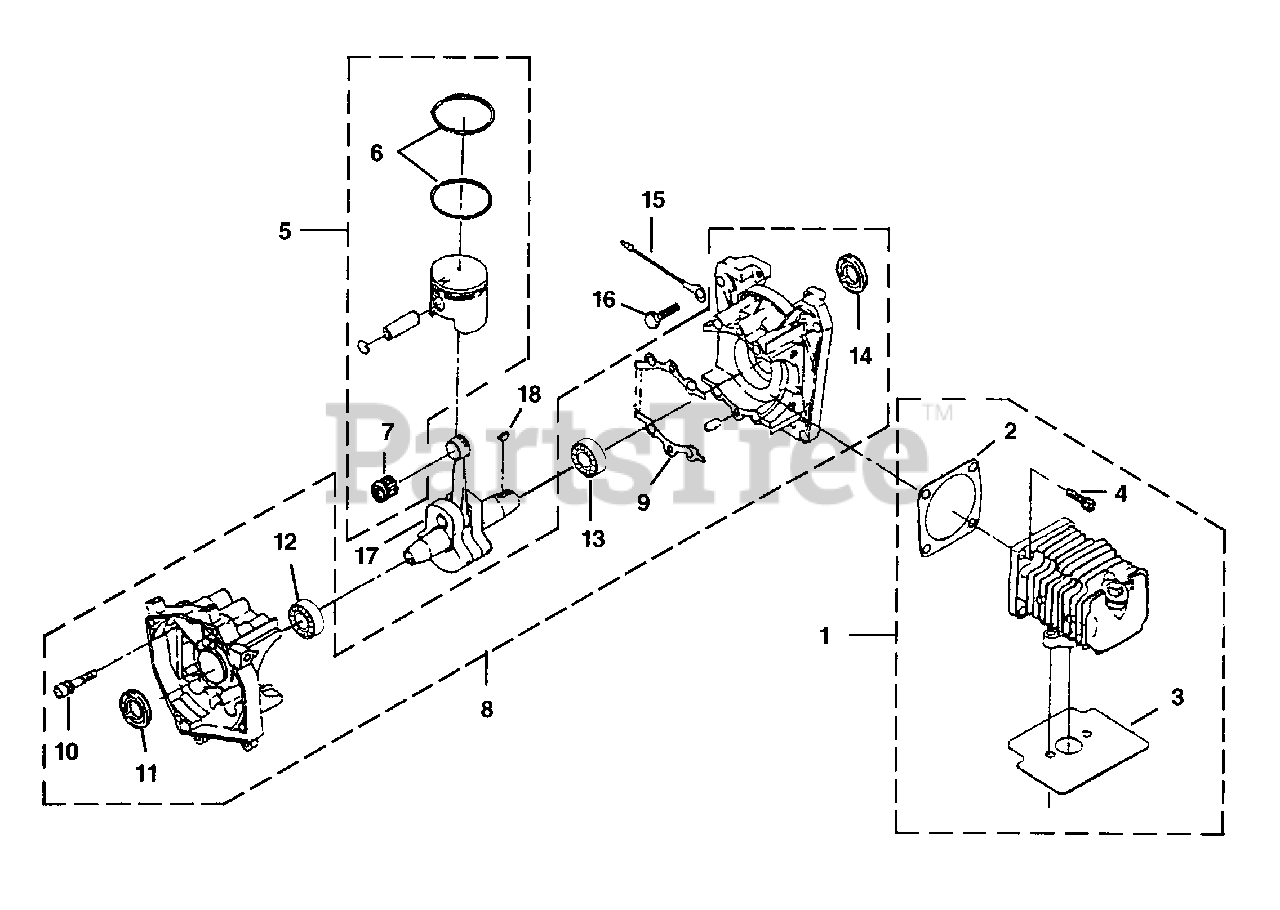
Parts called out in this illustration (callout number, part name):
1	CYLINDER ASSEMBLY
2	GASKET-Cylinder
3	GASKET-Muffler
4	SCREW-Socket Hd (M6 x 18)
5	PISTON ASSEMBLY
6	RING-Piston
7	BEARING-Wrist Pin
8	CRANKCASE ASSEMBLY
9	GASKET-Crankcase
10	SCREW-Socket Hd (M5 x 30 SW)
11	OIL SEAL
12	BALL BEARING
13	BALL BEARING
14	OIL SEAL
15	WIRE-Ground
16	BOLT ASSEMBLY (M6 x 25 SW)
17	CRANKSHAFT COMPLETE
18	WOODRUFF KEY
